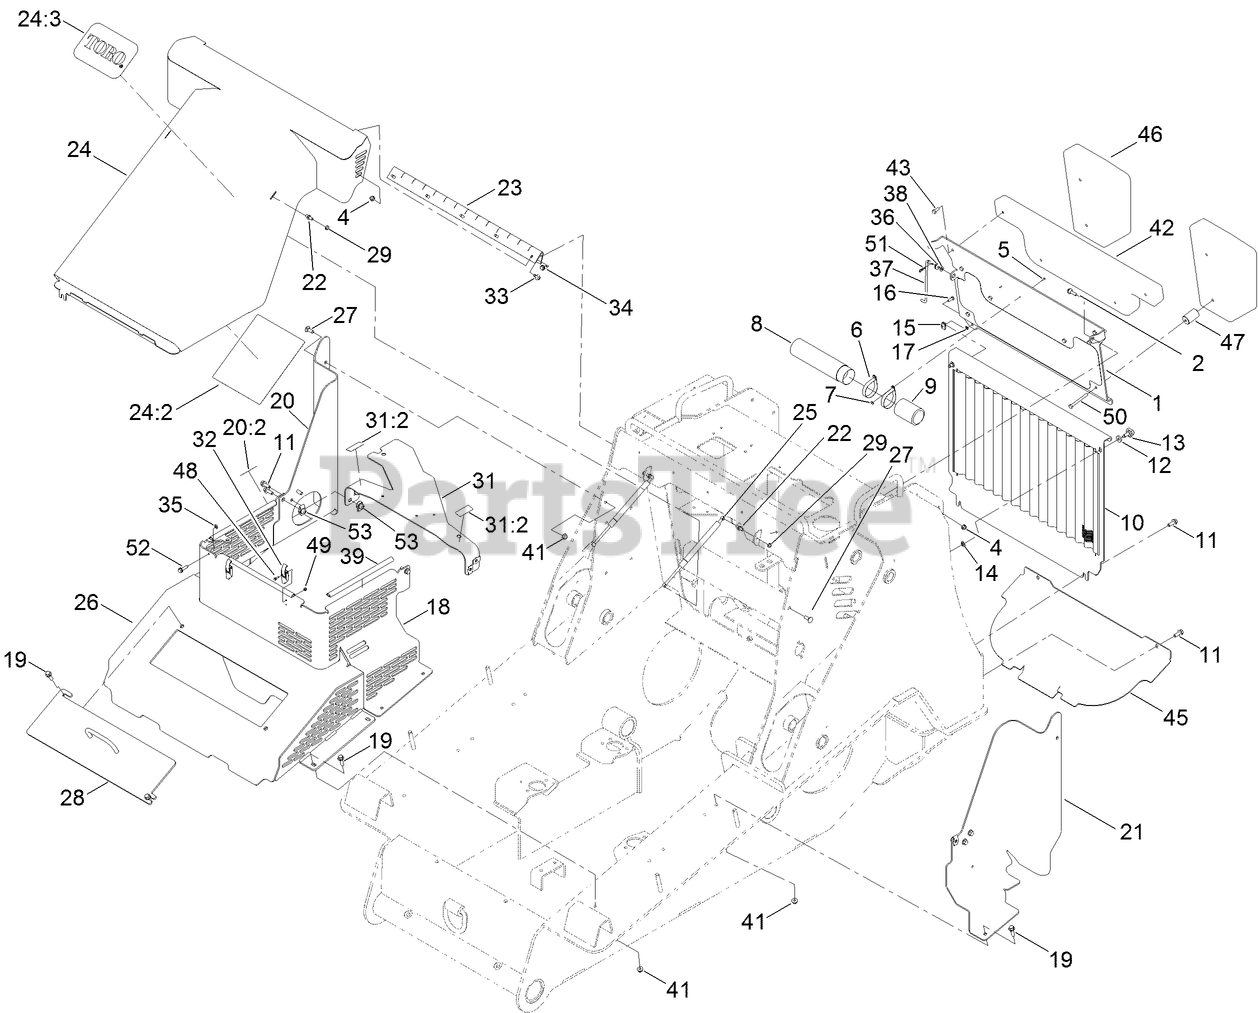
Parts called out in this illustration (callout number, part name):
1	PANEL-REAR
2	SCREW-SHOULDER
4	NUT-HF, NI
5	RIVET-POP
6	CLAMP-R
7	WASHER-BACK
8	TUBE-MANUAL
9	CAP-HOUSING
10	COVER-REAR
11	SCREW-HHF
12	WASHER-RUBBER
14	NUT-PUSH
16	SCREW-HH
17	NUT-RETAINING
18	GRILL-PANEL
19	SCREW-HHF
20	COVER-GRILLE, RH
20:2	DECAL-SURFACE, HOT
21	PANEL-SIDE, LH
22	STUD-BALL
23	HINGE-PIANO
24	HOOD ASM
24:2	DECAL-SERVICE
24:3	DECAL
25	CYLINDER-GAS
26	FRO0NT COVER ASM
27	BOLT-CARR
28	COVER PLATE ASM
29	NUT-LOCK, NI
31	BRACKET-AIR CLEANER
31:2	DECAL-SURFACE, HOT
32	LATCH-DRAW
33	SCREW-HHF
34	SCREW-HWH
35	RING-RETAINING, BOLT
36	GROMMET-RUBBER
37	ROD-PROP
38	WASHER-FLAT
39	LINER-FOAM
41	NUT-HF, NI
42	CUSHION-PAD
43	SCREW-HH
45	COVER-ACCESS, BOTTOM
46	PAD-REAR
47	SPACER-PAD
48	SCREW-HHF, SERRATED
49	NUT-LOCK
50	SCREW-HH
52	SCREW-HWHTF
53	NUT-TINNERMAN
